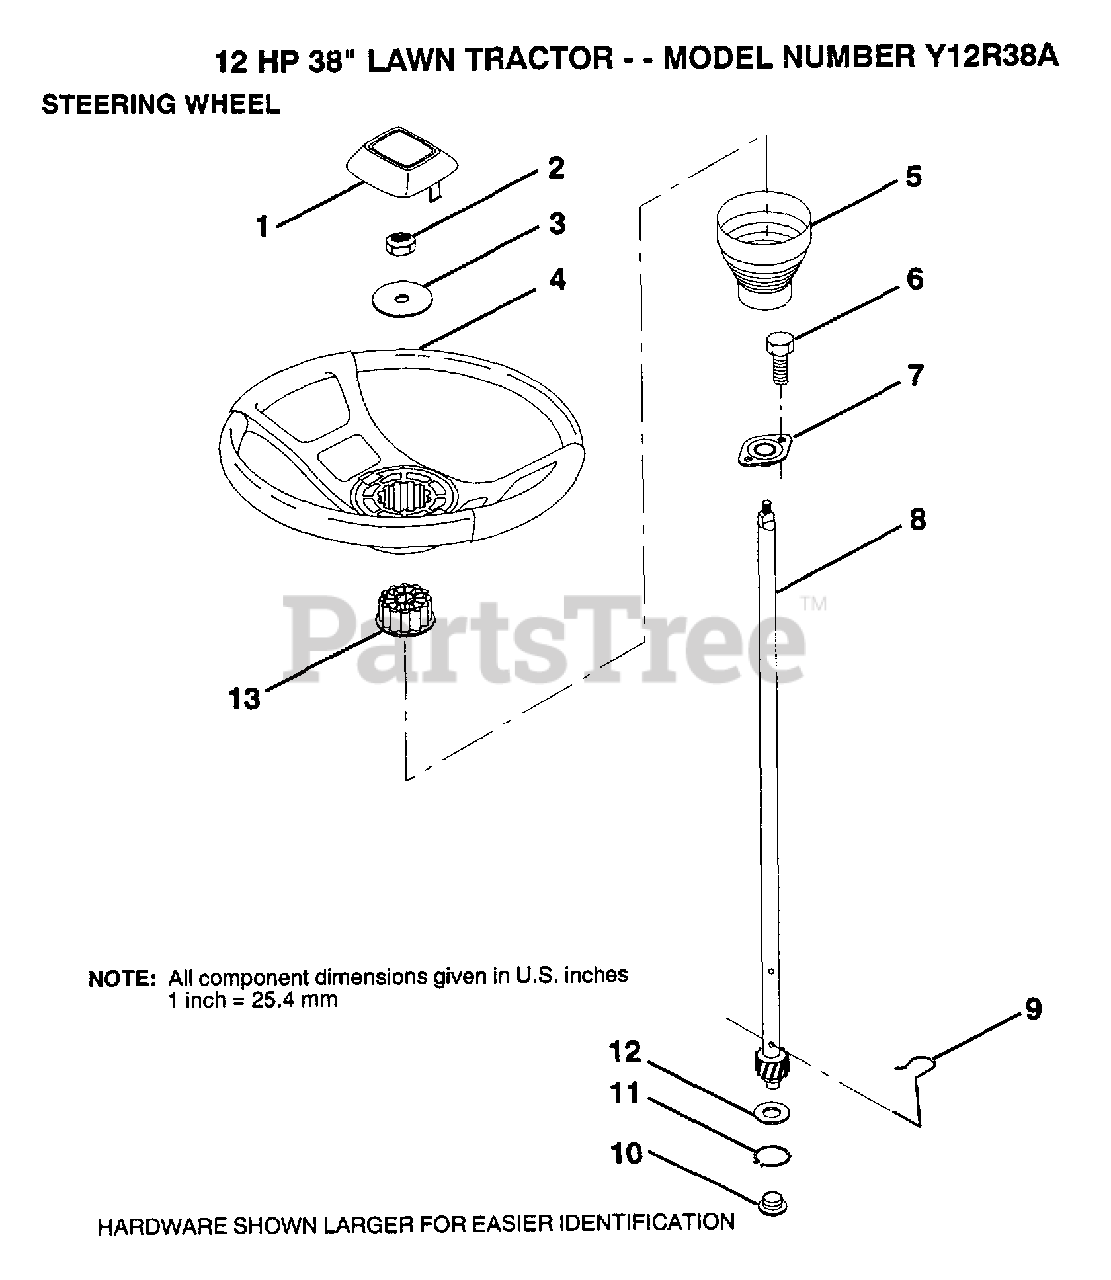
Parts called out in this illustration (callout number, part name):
1	INSERT STEERING
2	GRIPCO NUT
3	WASHER T
5	SLEEVE STEERING
9	STEERING CLIP
10	BUSHING STEER LWR
11	RING
12	WASHER LT
13	ADAPTER-WHEEL LT
